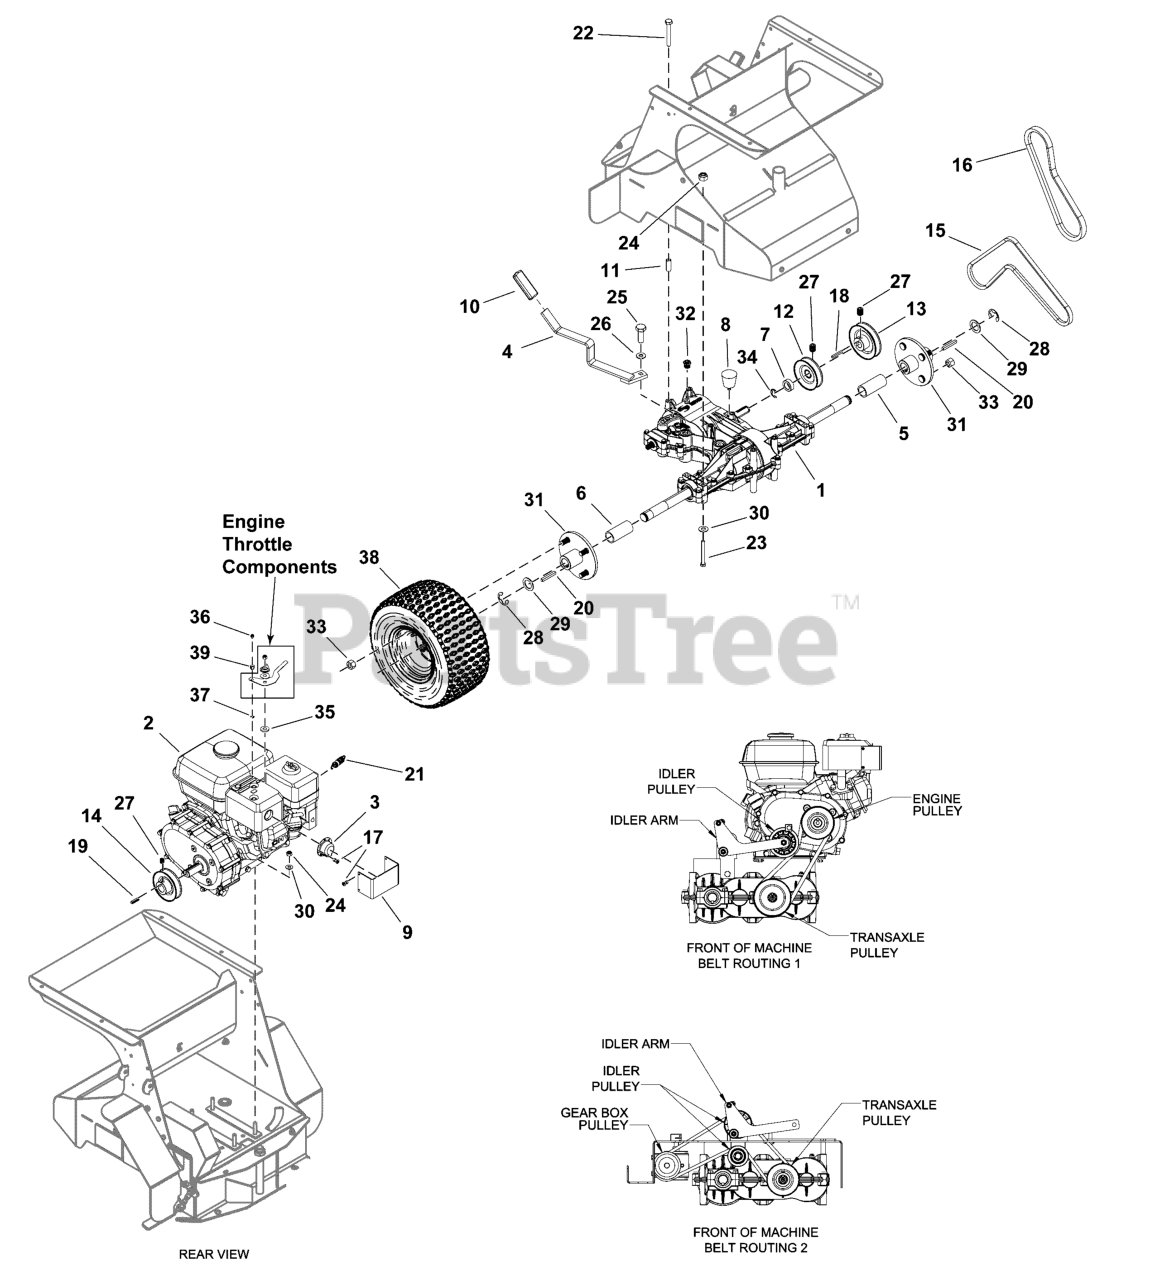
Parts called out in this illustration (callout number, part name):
1	TRANSMISSION, PEERLESS 855-007D
2	ENGINE, HONDA GX160UT2RH2
3	DEFLECTOR, EXHAUST HONDA GX160/GX200
4	WELD,LEVER,GEAR SHIFT, ROVER
5	SPCR-PVC 1.049" X 1.315" X 3.000
6	SPCR-PVC 1.049" X 1.315" X 2.850"
7	SPCR-UHMW .765" X 1.250" X .450"
8	BUMPER, 1.188OD X 1.50LG W/.3125-18 STUD
9	PLATE,MUFFLER SHIELD GX160
10	GRIP, .188" X 1.00" ID X .150" THK CLSD CELL FOAM
11	SPCR-SS, 304 0.370" X 0.500" X 1.350"
12	PULLEY, 3.50" O.D. x 0.750" I.D. V, A/B
13	PULLEY, 4.00" O.D. x 0.750" I.D. V, A/B
14	PULLEY, 3.50" O.D. x 0.875" I.D. V, A/B
14	PULLEY, Crankshaft
15	BELT, A-SEC, A39
16	BELT, V, B 29.80EL OHR ETH, PLY CD
17	RIVET, BLIND .125" X 250" SS188
18	KEY, .188" SQ. X 1.50" SS303
19	KEY, .188"-.250" STEPPED X 1.00" LONG SS 304
19	KEY, Drive Pulley
20	KEY, .250" SQ. X 2" SS188
21	SPRING, EXTENSION .25" OD X 1.00 LONG SS
22	SCR-CAP, HEX .3125"-18 X 2.250" SS188
23	SCR-CAP, HEX .3125"-18 X 3.000" SS188
24	NUT-HEX-NYLK, 0.3125"-18 SS188
25	SCR-CAP, HEX .250"-28 X 0.750" SS188
26	WSHR-SS, BLV .281"X.875"x.066
27	SCR-SH, SET .3125"-18 X .375" KCPT SS188
28	E-RING, 1.000" SHAFT YZ
29	WSHR-STL, FLT 1.000"X1.500"X.075" MAB ZP
30	WSHR-STL, FLT .343" X .750" X .050" SPC SS188
31	HUB, 1.00" BORE 4-BOLT X 4.00" BC
32	BREATHER VENT, .125"-27 PFT X .4375" HEX
33	NUT-LUG, .500"-20 ZP
34	E-RING, .750" SHAFT YZ
35	WASHER, Nylon, Flat, .385" X .880" X .125"
36	SCREW, HEX WASHER HEAD M4 X 0.7 - 6H
37	RING, RETAINING
38	ASM, WHEEL&TIRE 18" X 9.50" W/ANTI-FREEZE
38-1	TIRE, 18" TURF
38-2	Wheel Only
39	RETAINER, WIRE HEX 10MM
